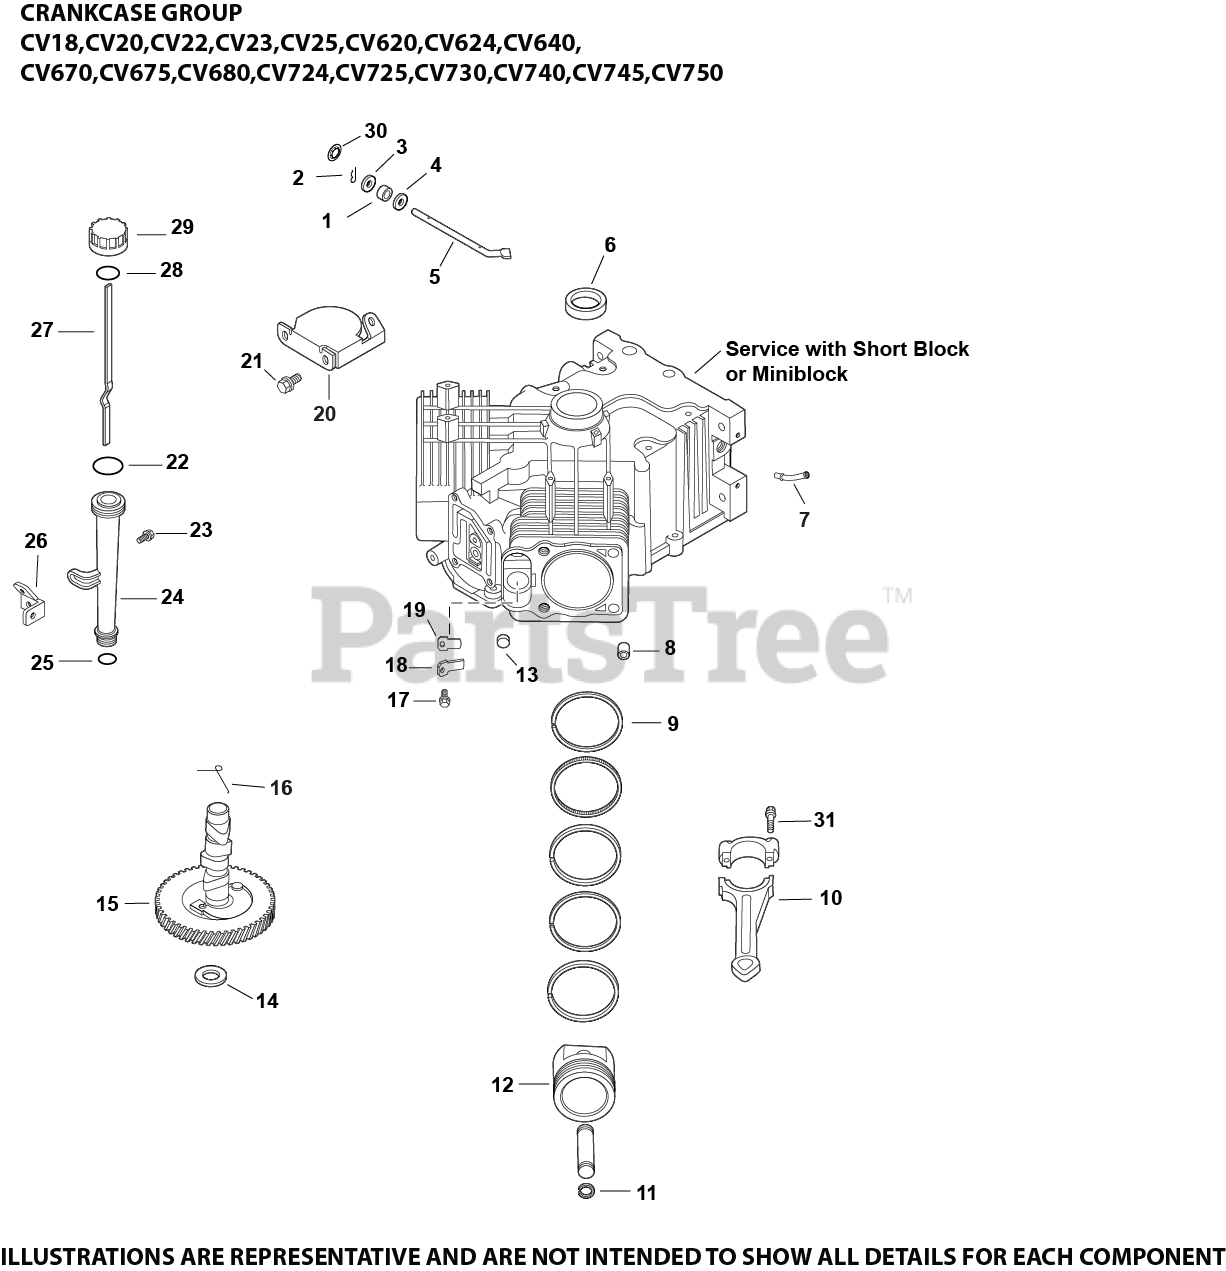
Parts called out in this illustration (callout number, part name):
1	SEAL, GOVERNOR CROSS SHAFT
3	WASHER, FLAT 9 MM
4	WASHER, FLAT 11/32"
5	SHAFT, GOVERNOR CROSS
6	SEAL, OIL (HELIX LIP)
8	PIN, LOCATING
9	RING SET (STD)1.5MM TOP RING THICKNESS (STYLE A)
9	RING SET (.08)1.5MM TOP RING THICKNESS - DISCONTINUED (STYLE A)
9	RING SET (.25)1.5MM TOP RING THICKNESS - DISCONTINUED, USE PISTON ASSEMBLY (STYLE A)
9	RING SET (.50)1.5MM TOP RING THICKNESS (STYLE A)
10	KIT, CONNECTING ROD ASSEMBLY USE 25 067 04-S
11	RETAINER, PISTON PIN
12	PISTON W/RINGS (STYLE A)(STD) - RING SET 24 108 22-S
12	PISTON W/RINGS (STYLE A)(.08) - RING SET 24 108 23-S - DISCONTINUED
12	PISTON W/RINGS (STYLE A)(.25) - RING SET 24 108 24-S
12	PISTON W/RINGS (STYLE A)(.50) - RING SET 24 108 25-S
13	PLUG, CUP
15	KIT, CAMSHAFT
17	SCREW, FLG THD FRM M5X.8X10
18	RETAINER, BREATHER REED
19	REED, BREATHER
22	O-RING, UPPER OIL FILL TUBE
24	TUBE ASSEMBLY
25	O-RING, LOWER OIL FILL TUBE
26	BRACKET, OIL FILL TUBE USE 24 126 243-S
27	DIPSTICK, ASSY
28	O-RING, DIPSTICK
29	KIT, OIL FILL CAP (BLACK)
30	RETAINER, RING
31	KIT, ROD BOLTS
